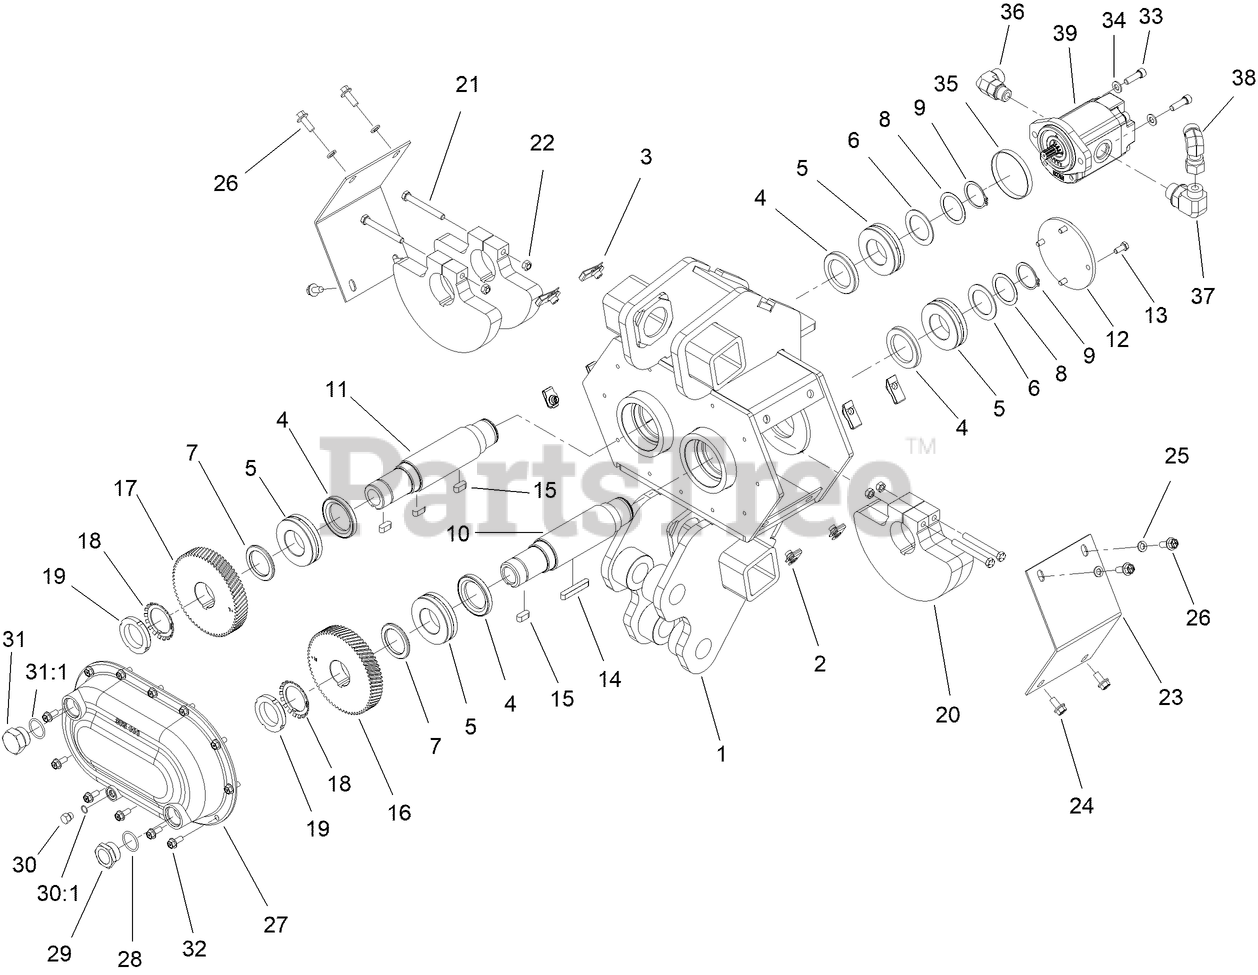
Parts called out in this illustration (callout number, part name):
1	VIBRATOR BOX - MACHINING
2	CLIP NUT (3/8-NC)
3	CLIP NUT (3/8-NC)
4	INTERNAL SEAL
5	BEARING-ROLLER, SPHERICAL
6	MACHINE BUSHING (1-3/4", 14GA)
7	SPACER
8	MACHINERY BUSHING (1.750")
9	EXTERNAL SNAP RING (1.750")
10	RIGHT SHAFT
11	DRIVER SHAFT
12	COVER PLATE
13	SCREW-HH
14	KEY (3/8" X 2-29/64")
15	KEY (3/8" X .980")
16	RIGHT GEAR
17	LEFT GEAR
18	TANG LOCK WASHER (1.792")
19	THRUST LOCKNUT (1.767-NF-18)
20	VIBRATOR WEIGHT
21	SCREW-HH
22	NUT-LOCK, NI
23	COVER PLATE
24	SCREW-HHF
25	WASHER-LOCK
26	SCREW-HHF
27	CASTING (SIDE COVER)
28	O-RING
29	SIGHT GAUGE (16S)
30	PLUG ASM
30:1	O-RING
31	FITTING-PLUG
31:1	O-RING
32	SCREW-HHF
33	SCREW-HSH
34	WASHER-FLAT
35	ADAPTER
36	FITTING-ELBOW, 90 DEG
37	FITTING-ELBOW 90
38	FITTING-HYD-90
39	Gear Motor ASM
